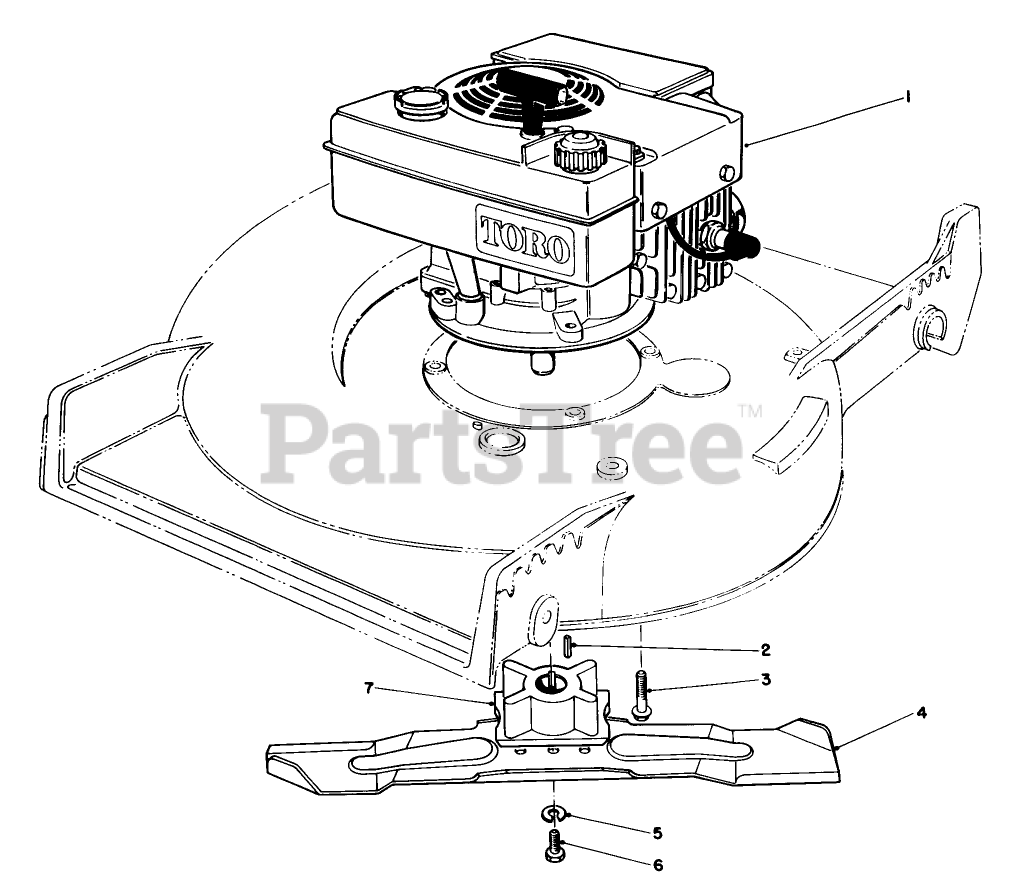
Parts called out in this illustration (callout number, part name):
2	KEY-SQUARE
3	3/8-16 X 2 CAPSCREW
4	BLADE-21in
5	WASHER-LOCK
6	SCREW-BLADE
7	BLADE RETAINER(DEEP)
